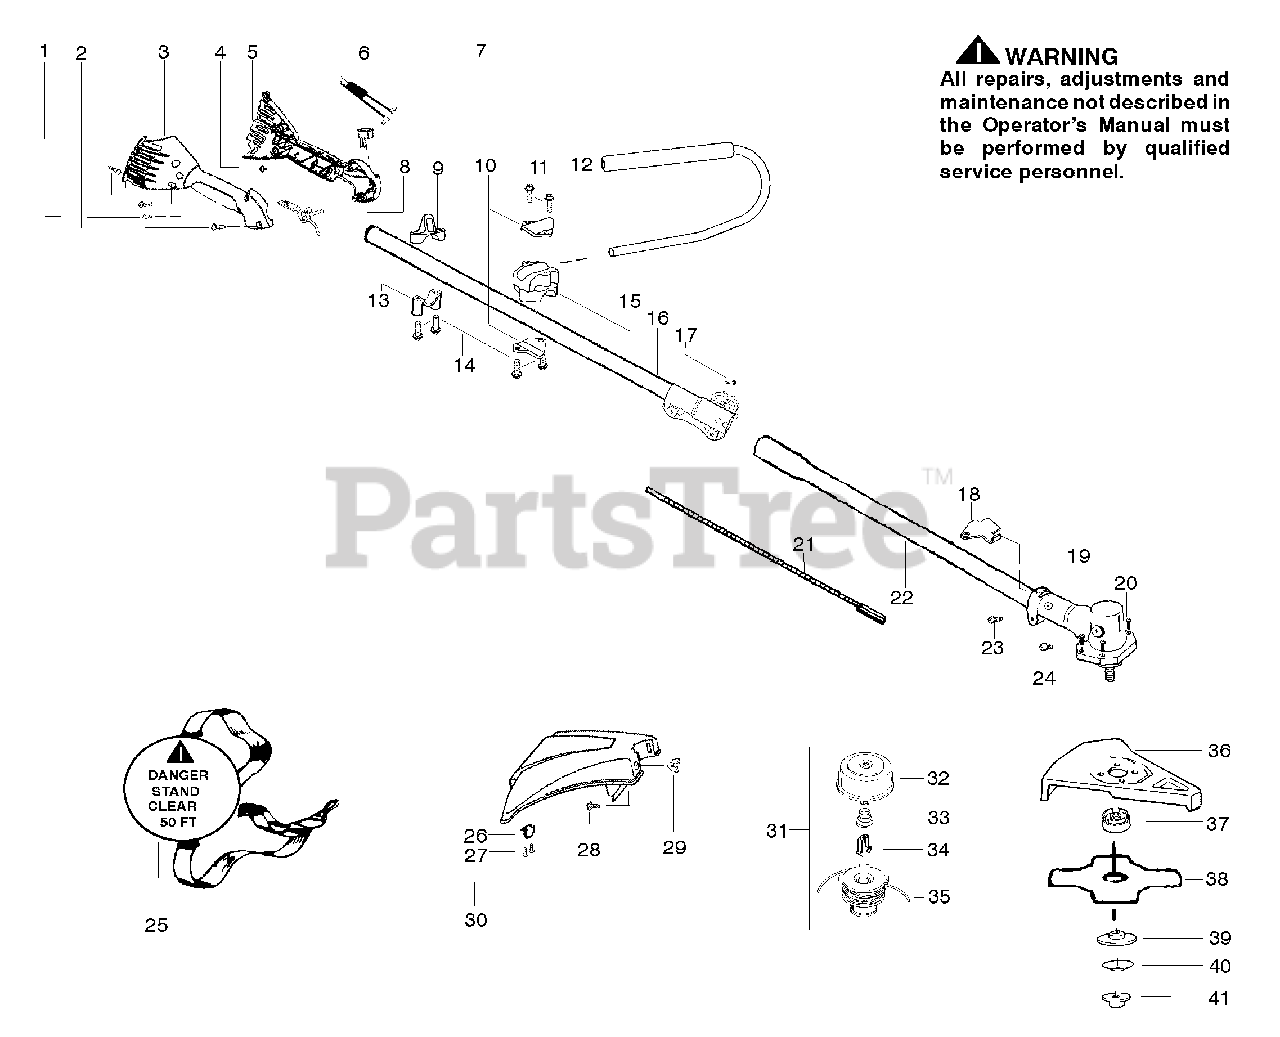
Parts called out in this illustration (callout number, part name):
1	Screw-alignment
3	Hsg.-Throttle-right
4	Screw-Cable Ret.
5	Hsg.-Throttle-left
6	Assy-Wire
7	Kit-Switch
8	Trigger-Throttle
9	Clamp-Harness
10	Clamp-Bracket
12	Assy.-Handlebar
13	Clamp-Harness
15	Clamp-Handlebar
16	Kit-Upper Shaft
18	Bracket-Shield
21	Shaft-Flex
22	Assy-Lower Shaft
25	Shoulder Strap
26	Limiter-Line
29	Wingnut
30	Kit-Shield Assy.
31	Accy-Cutting Head
32	Assy-Hub/Arbor
33	Spring-Return
34	Retainer-Spool
35	Accy-Wound Spool
36	Kit-Metal Shield
37	Dust cup
38	Accy.-Weed Blade
40	Washer-Belleville
41	Nut-Flange
